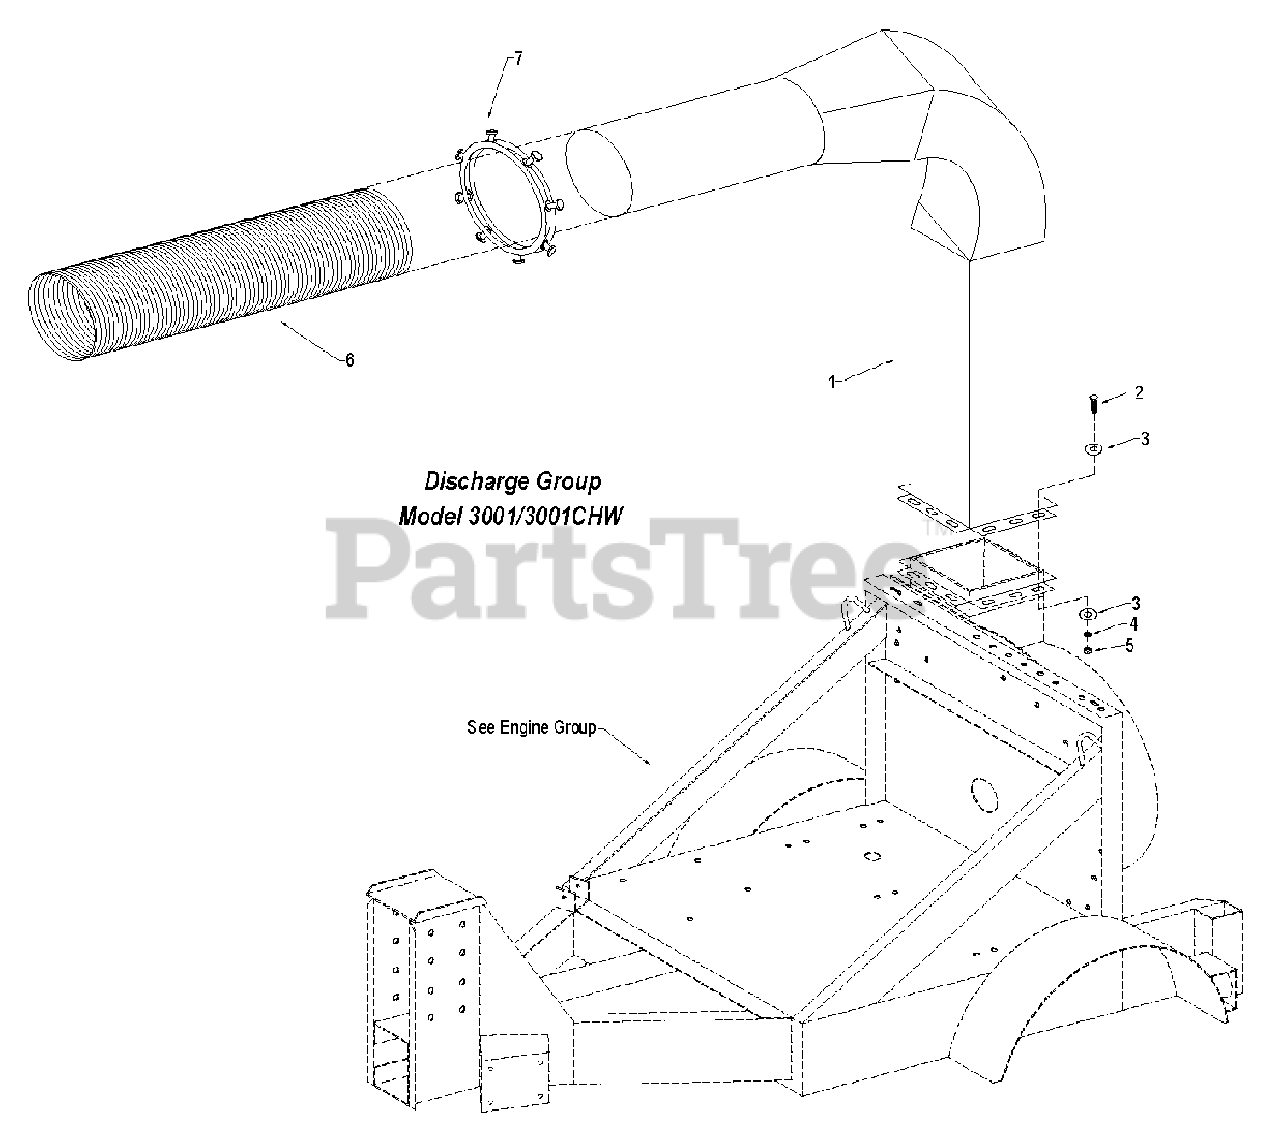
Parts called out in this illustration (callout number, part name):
1	Stack & Elbow Assembly
2	1/2-13 x 1-3/4 Hex Bolt
3	1/2 Flat Washer
4	1/2 Lock Washer
5	1/2-13 Hex Nut
6	Discharge Hose 12" x 6' Metal
7	Squeeze Ring 12"
